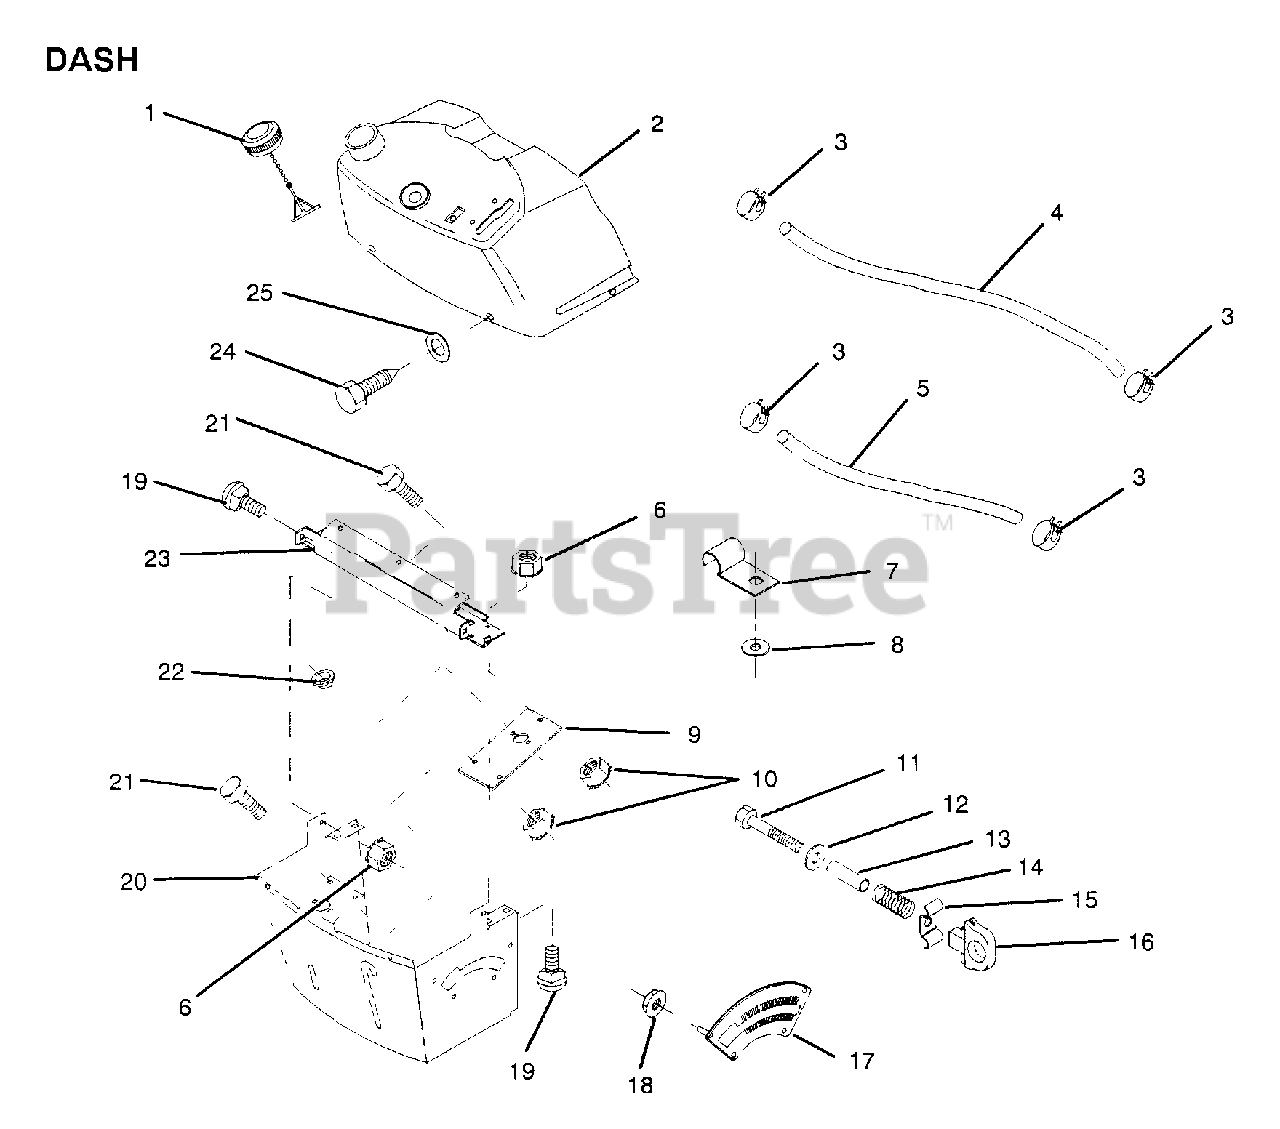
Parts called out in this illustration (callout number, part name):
3	HOSE CLAMP
5	FUEL LINE T
6	NUT
7	CLIP T
8	WASHER PM
9	"PLATE,SUPT "
10	LOCKNUT
11	BOLT
12	WASHER
13	SPACER SPLIT
14	SPRING T
15	HEIGHT ADJ
16	KNOB
17	ADJUSTER QUAD
18	NUT
19	BOLT
20	SUPPORT DASH
23	"BRAKE,CROSS"
